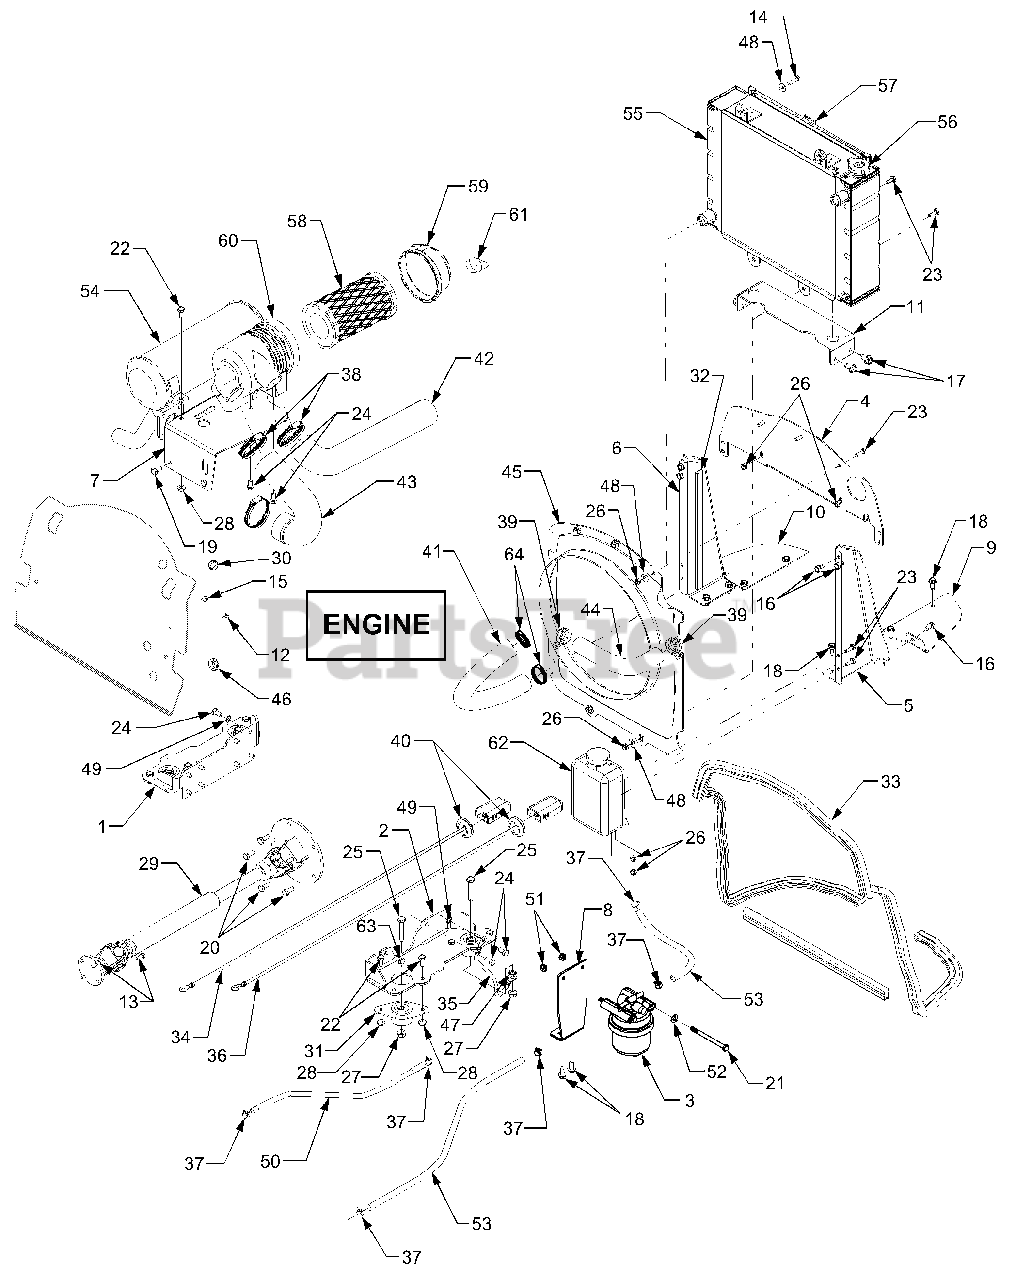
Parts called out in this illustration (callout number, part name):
1	Bracket, Engine LH
2	Bracket, Engine RH
3	Filter Assembly, Fuel
4	Plate, Radiator Baffle
5	Bracket, Radiator Mtg. RH
6	Bracket, Radiator Mtg. LH
7	Bracket, Muffler Mtg
10	Plate, Baffle, LH
11	Bracket, Radiator Mtg
12	Screw, Hex Wash Hd Tapp 10-16 x .5
13	Screw, Hex Cap, 1/4-20 x .62 GR5
14	Screw, Hex Cap 1/4-20 x 1.0 GR5
15	Screw, Hex Wash Hd Tapp 1/4-20 x .5
16	Screw, Hex Wash Hd Tapp 5/16-18 x .5
17	Screw, Hex Wash Hd Tapp 3/8-16 x .75
18	Screw, Hex Wash Hd Tapp 5/16-18 x .75
19	Screw, Hex Cap, M8-1.25 x 16
20	Screw, Hex Cap, M8-1.25 x 20
21	Screw, Hex Cap, 5/16-18 x 4.0 GR5
22	Screw, Hex Cap 5/16-18 x .75 GR5
23	Screw, Hex Cap 1/4-20 x .75 GR5
24	Screw, Hex Cap, M8-1.25 x 16
25	Screw, Hex Cap 3/8-16 x 2/0 GR5
26	Nut, Hex Insert Lock, 1/4-20
27	Nut, Hex Flange Lock, 3/8-16
28	Nut, Hex Flange Lock, 5/16-18
29	Shaft, Drive
30	Plug, Cap
31	Mount, Neoprene Engine
32	Tape, Foam, .625 wide
33	Seal, Heat Baffle
34	Wire, Battery Pos
35	Wire, Ground
36	Wire, Battery Neg.
37	Clamp, Hose
38	Clamp, Adjustable Hose
39	Clamp, Hose
40	Grommet, Hose Guard
41	Hose, Radiator to Engine
42	Hose, Air Filter
43	Hose, Air Inlet
44	Hose, Engine to Radiator
45	Shroud, Fan
46	Grommet, Rubber
47	Washer, External Lock, 3/8
48	Washer, Flat, .28 x .74 x .063
49	Washer, External Lock, 5/16
50	Hose, Fuel Line
51	Nut, Hex Insert Lock, 5/16-18
52	Washer, Flat, .344 x .688 x .065
53	Fuel Line, 5/16 ID
54	Muffler, Engine
56	Cap, Radiator, 13psi
57	Screen, Debris
58	Element, Air Cleaner
59	Cap, Air Cleaner
60	Cannister, Air Cleaner
61	Nozzle, Air Cleaner
62	Bottle, Overflow
63	Screw, Hx Cap, M8-1.25:25 GR8
64	Clamp, Hose
